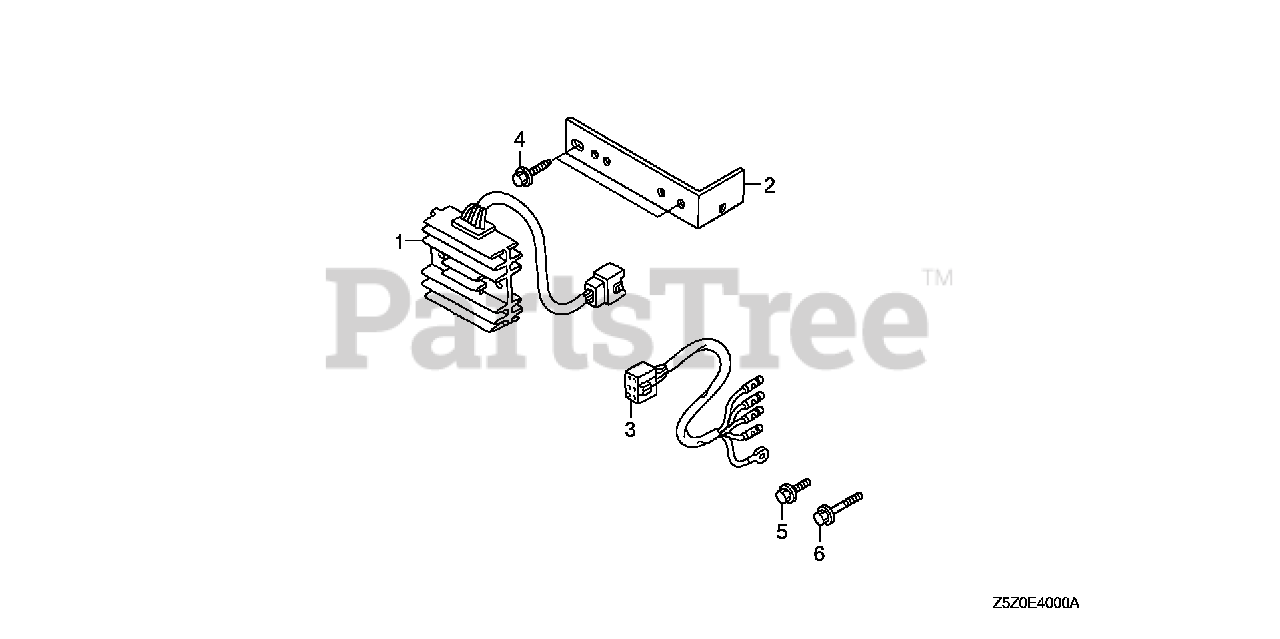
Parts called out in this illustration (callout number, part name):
1	RECTIFIER ASSY., REGULATOR
2	BRACKET, REGULATOR
3	SUB-WIRE HARNESS ASSY.
4	BOLT, FLANGE (6X14) (CT200)
5	BOLT, FLANGE (6X8)
6	BOLT, FLANGE (6X20)
